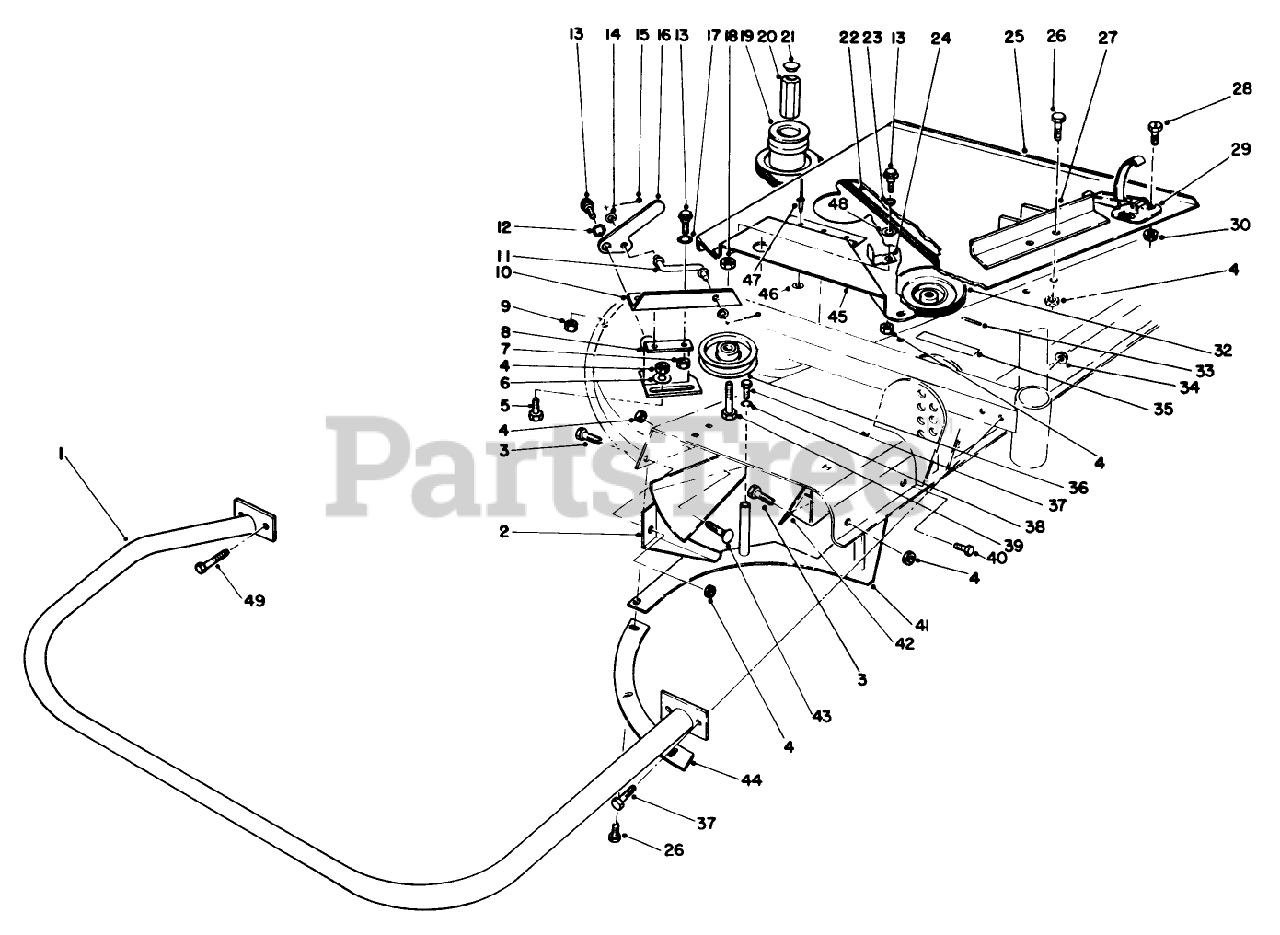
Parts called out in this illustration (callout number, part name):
1	Bumper
2	Deflector Rear
3	SCREW-HH
4	NUT-LOCK, CONE
5	SCREW-HH
6	WASHER-FLAT
7	NUT-LOCK, NI
8	Bracket-Idler
9	NUT-LOCK, CONE
10	Slide-Idler
11	Idler Rod
12	WASHER-SPRING
13	SCREW-SHOULDER
14	WASHER-PLAIN
15	PIN-COTTER
16	Lever-Idler
17	WASHER
18	NUT-LOCK, NI
19	Pulley (Splined)
20	NUT-PULLEY
21	NUT-COVER
22	V-BELT
23	WASHER-SPRING
24	Latch
25	Cover Assembly RH (Incl. Ref. #4, 13, 23, 24, 28-30 & 45-48)
26	SCREW-HH
27	Bracket-Spring
28	SCREW-HWH
29	CLAMP-SLOTTED
30	NUT-LOCK, FLANGE
31	NUT-HEX, SIDE DEFORM
32	Pulley-Gear Box
33	PIN-ROLL, SLOTTED
34	NUT-FLANGE
35	WARNING DECAL
36	PULLEY-IDLER
37	SCREW-HH
38	WASHER-LOCK
39	SCREW-HH
40	SCREW-HH
41	Rear Shelf
42	Deflector-Front
43	BOLT-CARR
44	Shelf-RH
45	Cover-Pulley
46	WASHER
47	RIVET-POP
48	WASHER-FLAT
49	SCREW-HH
